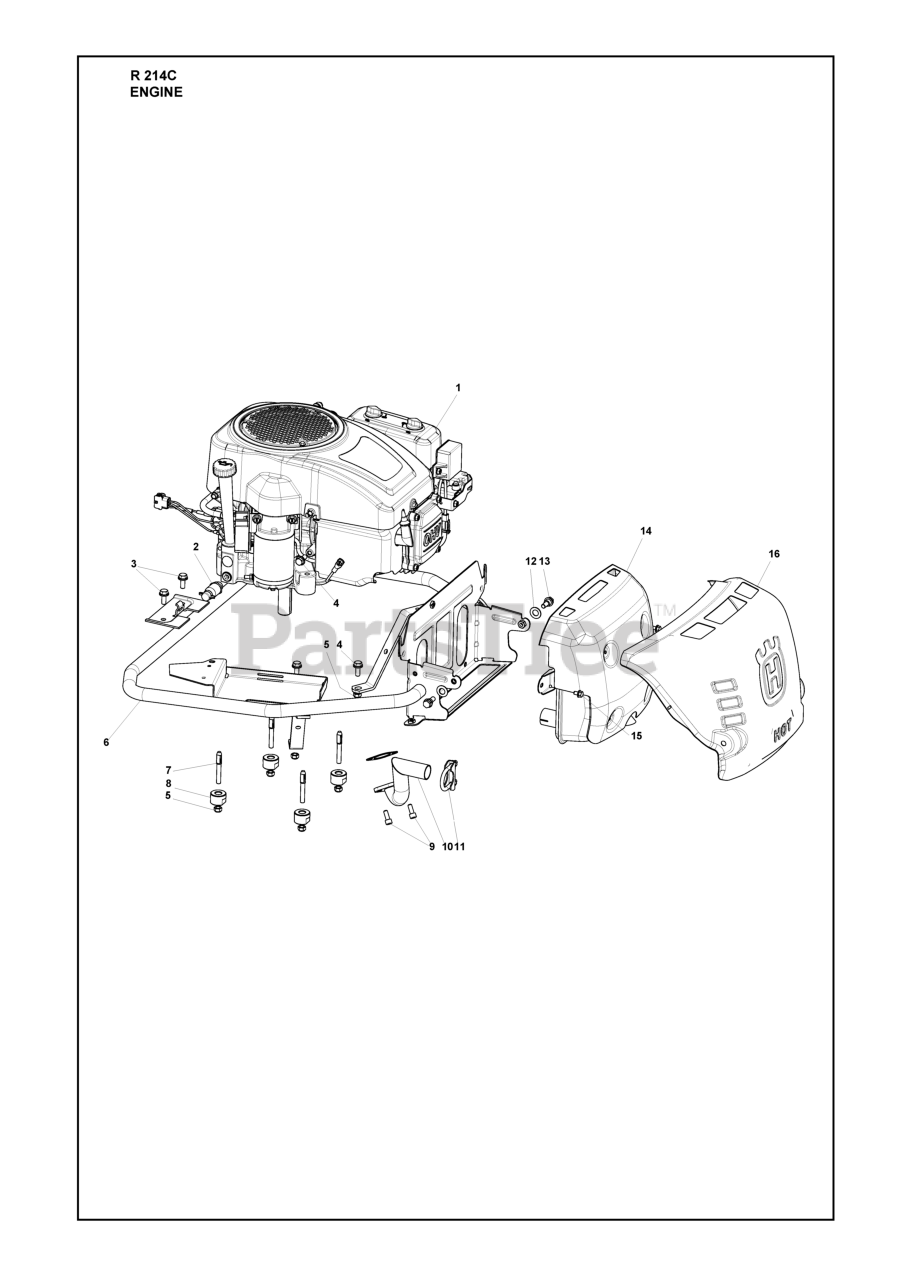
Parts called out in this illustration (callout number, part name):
2	VALUE.OIL.DRAIN
2	KEY 1/4 X 2.5
4	LOCKNUT M8
7	HUB.ASM.WHEEL.REAR.23"TEX
8	EXHAUST GASKET
11	CLAMP ASSY EXHAUST
12	SPRINGWASHER
15	WASHER
16	HEAT SHIELD
17	SPRING.BRAKE.HG3000/3500
26	SPRING.RETURN.CRUISE
29	ROD.BRAKE.HG3000/3500
33	E RING HYT
35	ROD.BRAKE.PARKING.GT.H
42	PEDAL COVER T
50	IDLER.FLAT.910.OFFSET
51	NUT LOCK FLG 3/8-16 UNC
52	IDLER.V-GROOVE.910.OFFSET
56	BELT.V.GROUND.DRIVE
64	SHAFT.ASM.PEDAL.BRK.CNTR
70	RP CONSOLE.ASM.PCH.W/TB
73	BOLT HEX FLGHD 5/16-18X3 GR. 5
74	SCREW.HI-LO.CONSOLE
92	BOLT
106	CAP, VENT ASSY
114	NUT.71038.31-18.HEX.NYLOCK
116	NUT LOCK HEX FLANGE 5/16-18
121	BRACKET STRAP TORQUE
122	BOLT.5/16-18X2.5
125	SCREW
142	STRAP.TORQUE.HG3000/K46
143	Screw 5/16-18 x 1/2 Hex, Self Tapping 5/16-18 x 1/2
145	WASHER.AXLE.FLANGE.HG-3000
153	RETAINER M
158	KEEPER BELT
159	COTTER PIN
160	RETAINER CLIP
161	SPRING, RETURN LT
166	NUT.PUSH.625.2006
167	LATCH.BRAKE.SPRING
170	KEEPER.V-IDLER.CENTER.
184	HANDLE.PARKG.BRK.HUSQ X667
186	SPACER.RETAINER
187	WASHER 12/32X2X10GA
188	RP.LINK.CLUTCH.GROUND.DRIVE
189	BELLCRANK.GROUND.DRIVE.TEX.
190	KEEPER.BELLCRANK.DRIVE
195	RETAINER.ROD.BRAKE.HG3000.TEX
196	SCREW 3/8-16X1
197	BRKT.ANIT-ROTATION.CLUTCH
203	WASHER
206	BRKT.MOUNT.LATCH.CRUIS
207	LATCH.CONTROL.CRUISE
208	GEAR.SECTOR.CONTROL.CR
209	ROD.CONTROL.CRUISE.GT.
210	ROCKER.ASM.PEDAL.CONTR
211	BEARING.NYLON
213	KNOB.CONTROL.CRUSIE.HU
214	PEDAL.FORWARD.TEX.GT.4
215	PEDAL.REVERSE.TEX.GT.4
216	BRACKET.PULLEY.IDLER.W/TEX
220	REFLECTOR.RH.TEX GT
221	RETAINER.SPRING.CLIP.H
222	WASHER
